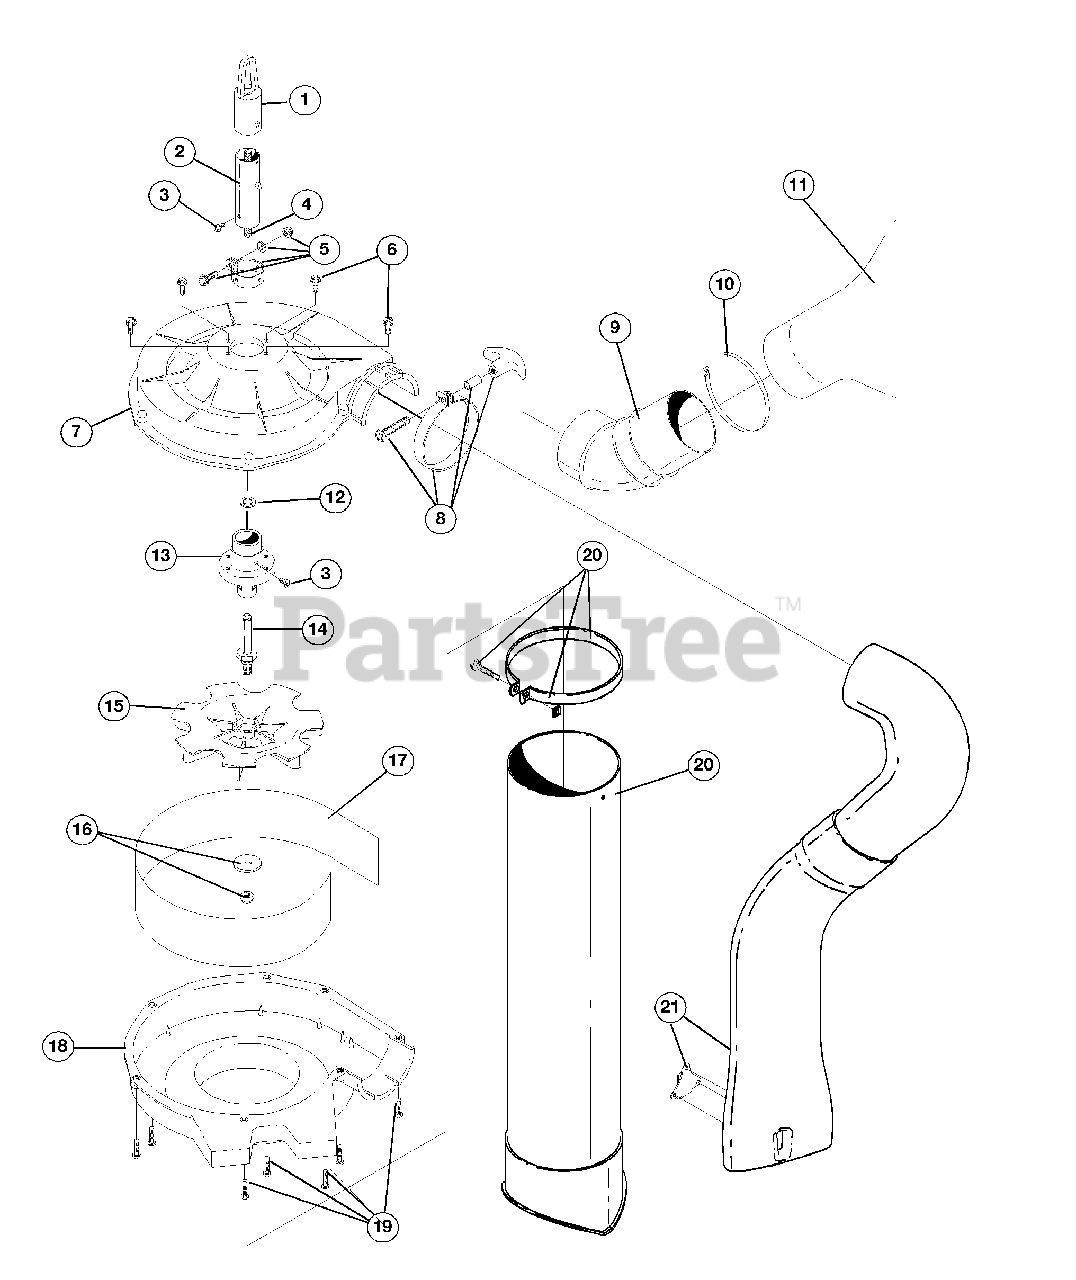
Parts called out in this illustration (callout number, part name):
1	Hanger
2	Boom Assembly
3	Anti-Rotation Screw
4	Drive Shaft Assembly
5	Lower Clamp Assembly
6	Mounting Screw
7	Upper Housing
8	Clamp Assembly
9	Adapter
11	Vacuum Bag Assembly
12	Palnut
13	Bushing Housing Assembly
14	Impeller Shaft
15	Impeller
16	Nut and Washer Assembly
18	Lower Housing
19	Mounting Screw
20	Vacuum Tube Assembly
21	Blower Tube Assembly
